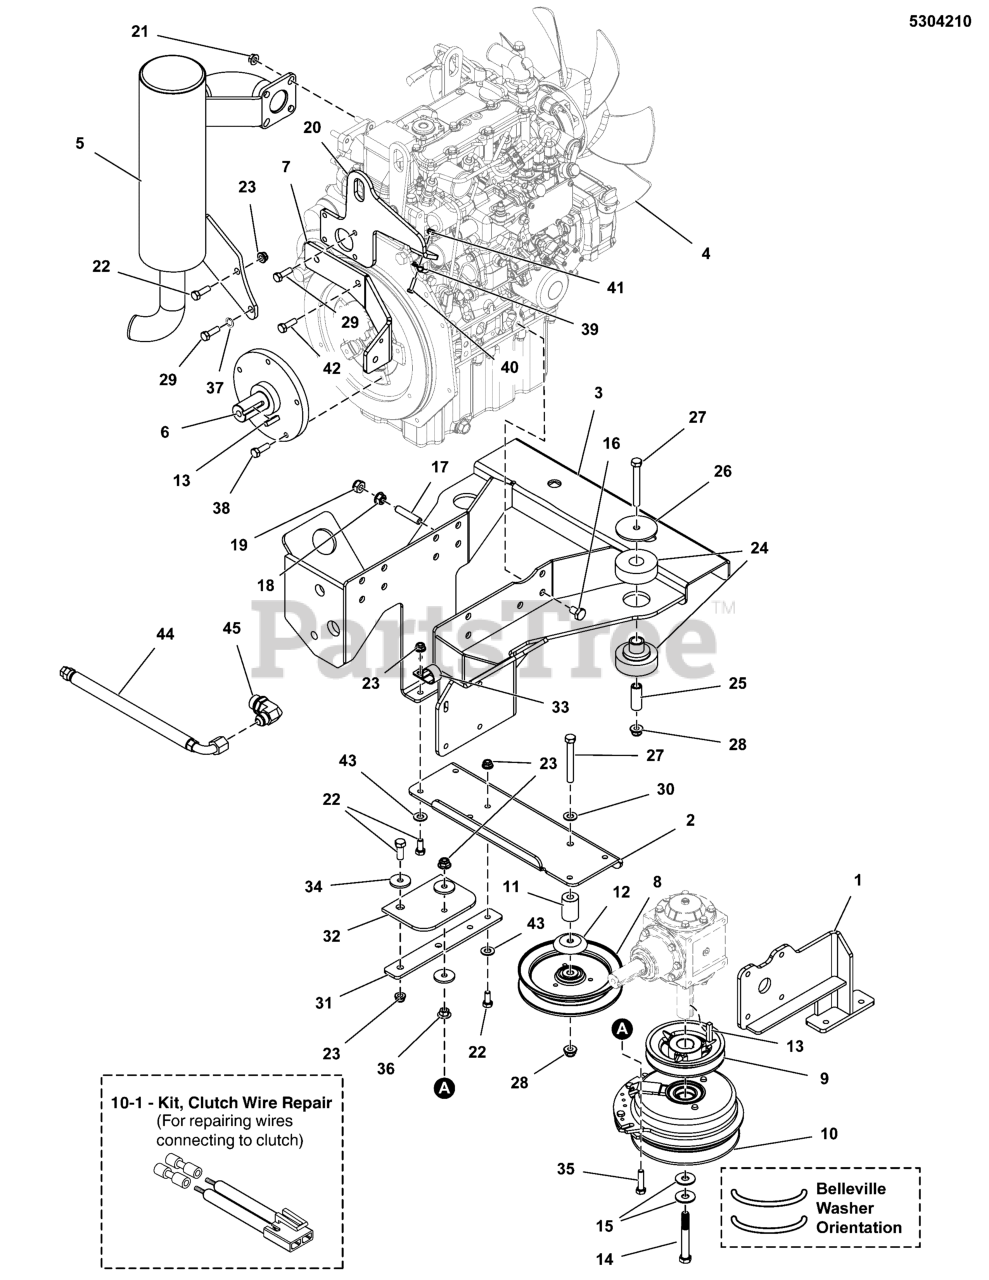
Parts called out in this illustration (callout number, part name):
1	WELD, CLUTCH ANCHOR PLATE BRACKET - RED
2	PLATE, CLUTCH ANCHOR - BLK
3	WELD, ENGINE MOUNT, IS2600Z - RED
5	MUFFLER, YANMAR 3TNM74F, IS2600
6	SHAFT, STUB, IS2600Z
7	SPRING ANCHOR, YANMAR ENGINE, 2600 - BLK
8	PULLEY, C-SEC, V-IDLER, 6.25"ODX3/8ID
9	PULLEY, 4.75OD X 1"BORE, ZP
10	CLUTCH,WARNER, 200FT-LB, 1.0"
10-1	KIT, CLUTCH WIRE REPAIR
11	SPACER, .39 X 1.00 X 1.47, YZ
12	SHIELD, BEARING PULLEY, 3/8ID, CZ
13	KEY, 1/4" SQ. X 1-1/4
14	BOLT, CRANKSHAFT, 7/16-20 X 3, GD8
15	BELLEVILLE WASHER, 1.1875 X .442 X .098
16	BOLT, M10-1.5 X 16MM GD8.8
17	SOCKET SET SCREW, M10-1.5 X 50, SS, CAP PT
18	HEX NUT, FLG, M10-1.5 SER CZ, NO SEALER
19	HEX NUT, M10-1.5 NYLON INSERT
20	PLATE, THROTTLE, IS2600 3TNM74F - BLK
21	NUT, M8-1.25 Hex Serrated Flange
22	BOLT, 5/16-18 X 1" GRD5 YZ
23	NUT, 5/16-18 HEX NYLOCK FLANGE NUT
24	ISO MOUNT, 215 LBS, YELLOW, 60272-1
25	SPACER, .38 x .62 x 1.62
26	WASHER, .39 X 2.50 X .125
27	BOLT, 3/8-16 X 3" GD5 CZ
28	NUT, 3/8 - 16 HEX NYLOCK FLANGE
29	BOLT, M8-1.25 X 25MM GR 8.8
30	WASHER, 3/8 SAE
31	MOUNT, CLUTCH ANCHOR- BLK
32	CLUTCH ANCHOR PAD
33	CLAMP, TUBE & WIRING, 1.062 ID
34	WASHER, .34 X 1.25 X 10 GA
35	BOLT,5/16-18X1.500,CARRIAGE,SQ,GR5,ZC/CL
36	NUT, 5/16-18 HEX SERRATED FLANGE (LARGE)
37	WASHER, 5/16 LOCK CZ
38	BOLT, M8-1.25 X 20 MM GD 8.8
39	CLAMP, CONDUIT
40	SCREW, #10-24 X 3/4" ROUND PHILLIPS
41	NUT, Hex, Nylon Lock, #10-24
42	BOLT, M10 X 25MM GR 8.8
43	WASHER, 5/16" SAE
44	HOSE, OIL DRAIN, 24HP YANMAR
45	FITTING, #8JIC - M16X1.5, ELBOW
